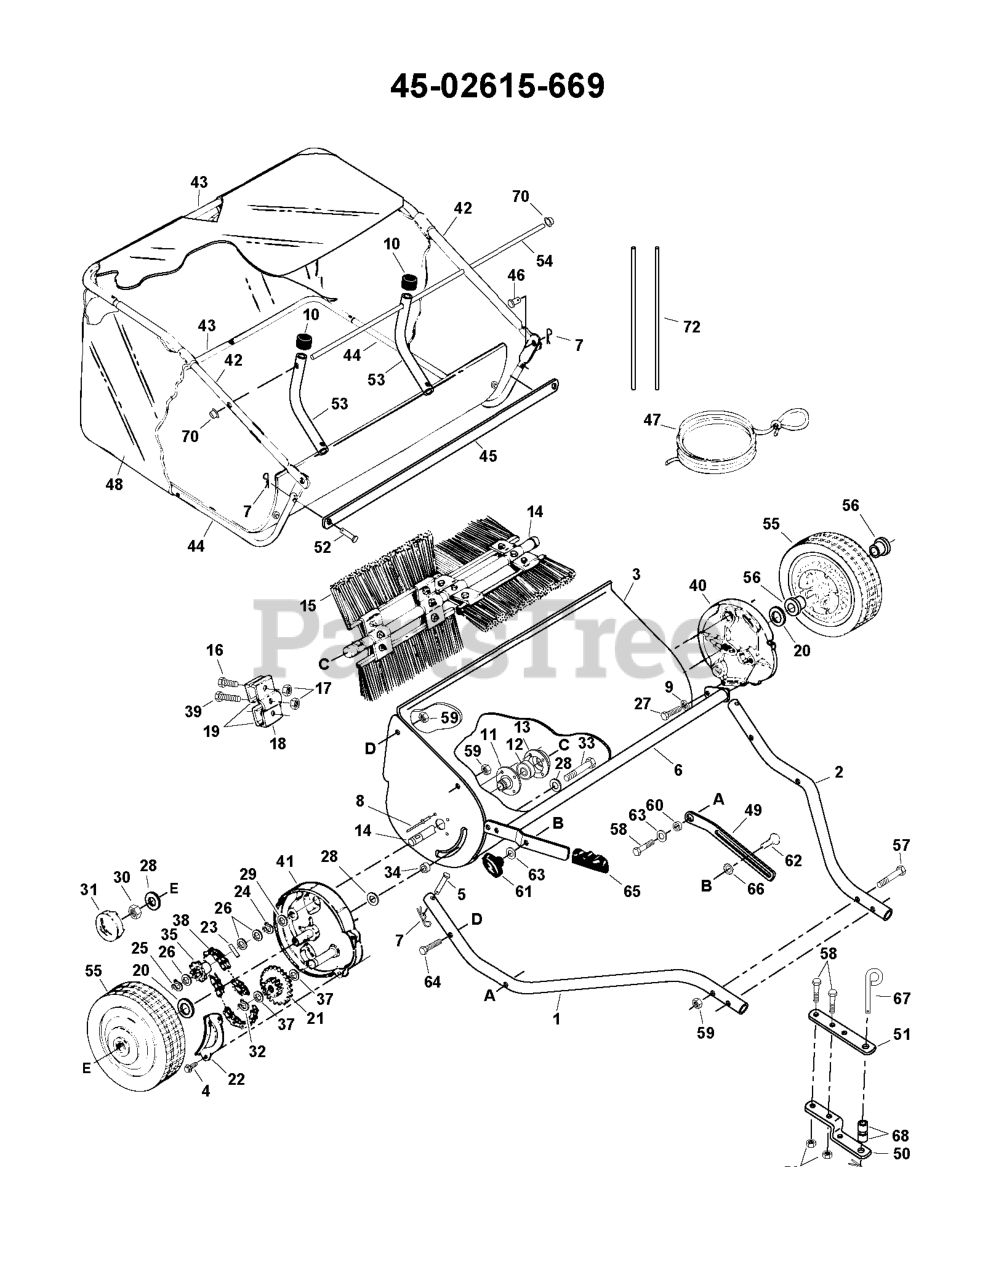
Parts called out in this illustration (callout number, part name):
9	LOCK WASHER
11	BRUSH BUSHING ASSY
21	GEAR SPRUCKET SUB ASSY
22	Dust Cover
24	Ring, Retaining 3/4"
29	FL-WASHER
33	HEX BOLT
34	Spacer 13/32" x 5/8" x 3/16"
36	RATCHET SPROCKET
37	Washer, 1/2" x 1" x .02"
38	ROLLERCHAIN 3/8X1/2"
48	ASS'Y HOPPER BAG (22 CU. FT)
53	TUBE.BAG.ARM.AGRI-FAB
55	WHEEL & TIRE ASSY CPL
56	BEARING
67	Pin, Hitch
72	HOPPER SUPPORT ROD
